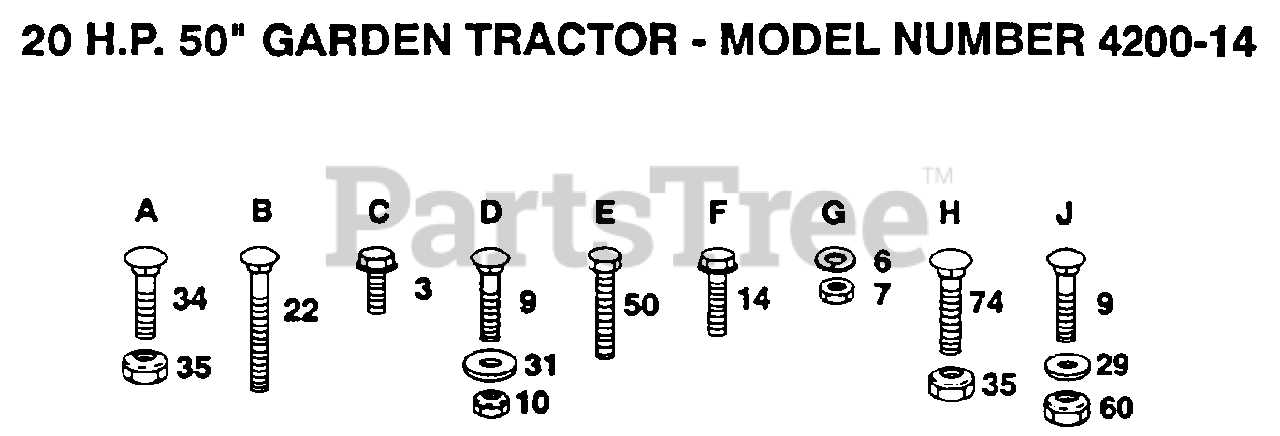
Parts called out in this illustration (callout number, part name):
3	SCREW LT
6	LOCKWASHER
7	NUT.HEX.5/16-18
9	BOLT
14	SCREW
22	BOLT
29	WASHER M
31	WASHER
34	BOLT
50	BOLT
74	BOLT
